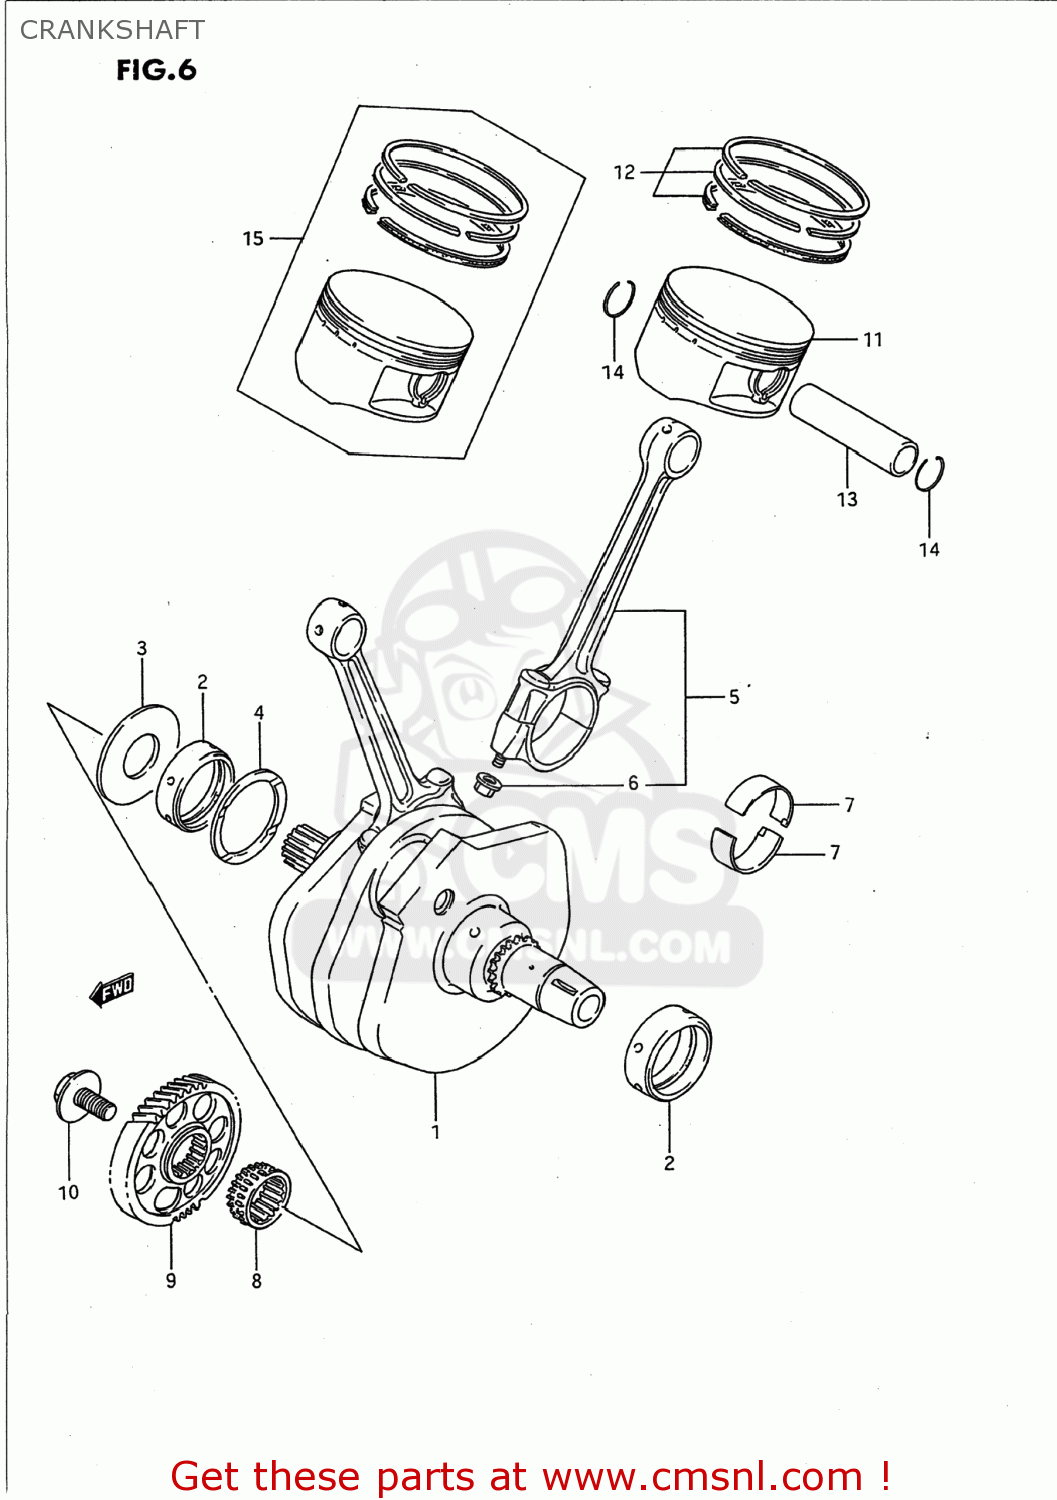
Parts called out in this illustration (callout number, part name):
1	CRANKSHAFT SET
2	METAL,CRANKSHAFT
3	WASHER,CRANK THRUST
4	PLATE,CRANK THRUST
5	CONNECTING ROD ASSY
6	NUT
7	METAL,CRANK PIN
8	SPROCKET,CAM CHAIN DRIVE,R
9	GEAR,PRIMARY DRIVE
10	BOLT(14X28)
11	PISTON (94.00MM)
12	RING SET,PISTON
13	PIN,PISTON
14	CIRCLIP
15	PISTON SET(OS:0.5)
